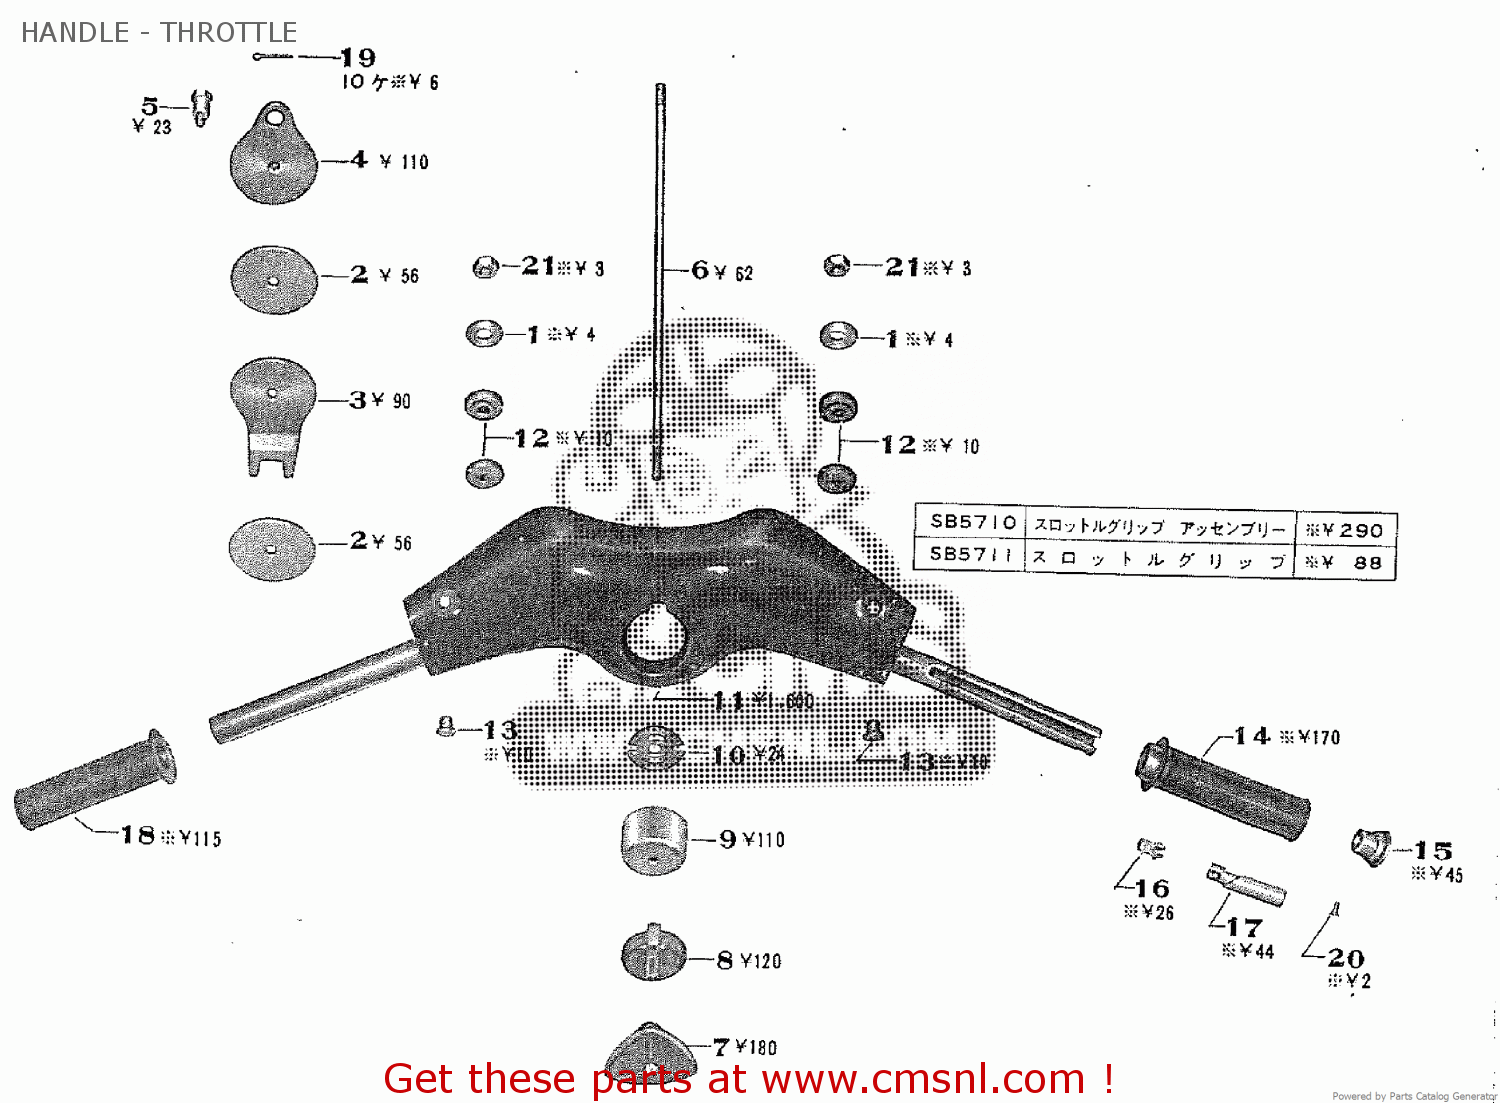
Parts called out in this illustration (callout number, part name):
1	WASHER
2	DAMPER FRICTION FACING
3	DAMPER HOOK PLATE
4	DAMPER FRICTION PLATE COMP.
5	FRICTION PLATE LOCK PIN
6	DAMPER ROD
7	DAMPER NOB COMP.
8	DAMPER NOB ADJUSTER COMP.
9	DAMPER ADJUSTER COMP.
10	DAMPER RING
11	STEERING HANDLE RUBBER
12	RUBBER
13	FACE PLATE SET BOSS CAP
14	THROTTLE GRIP
15	THROTTLE TUBE
16	THROTTLE GRIP CAP
17	THROTTLE END PIECE
18	THROTTLE SLIDING PIECE
19	LEFT GRIP
20	5X10 CROSS SCREW
21	10MM HEXAGON NUT
